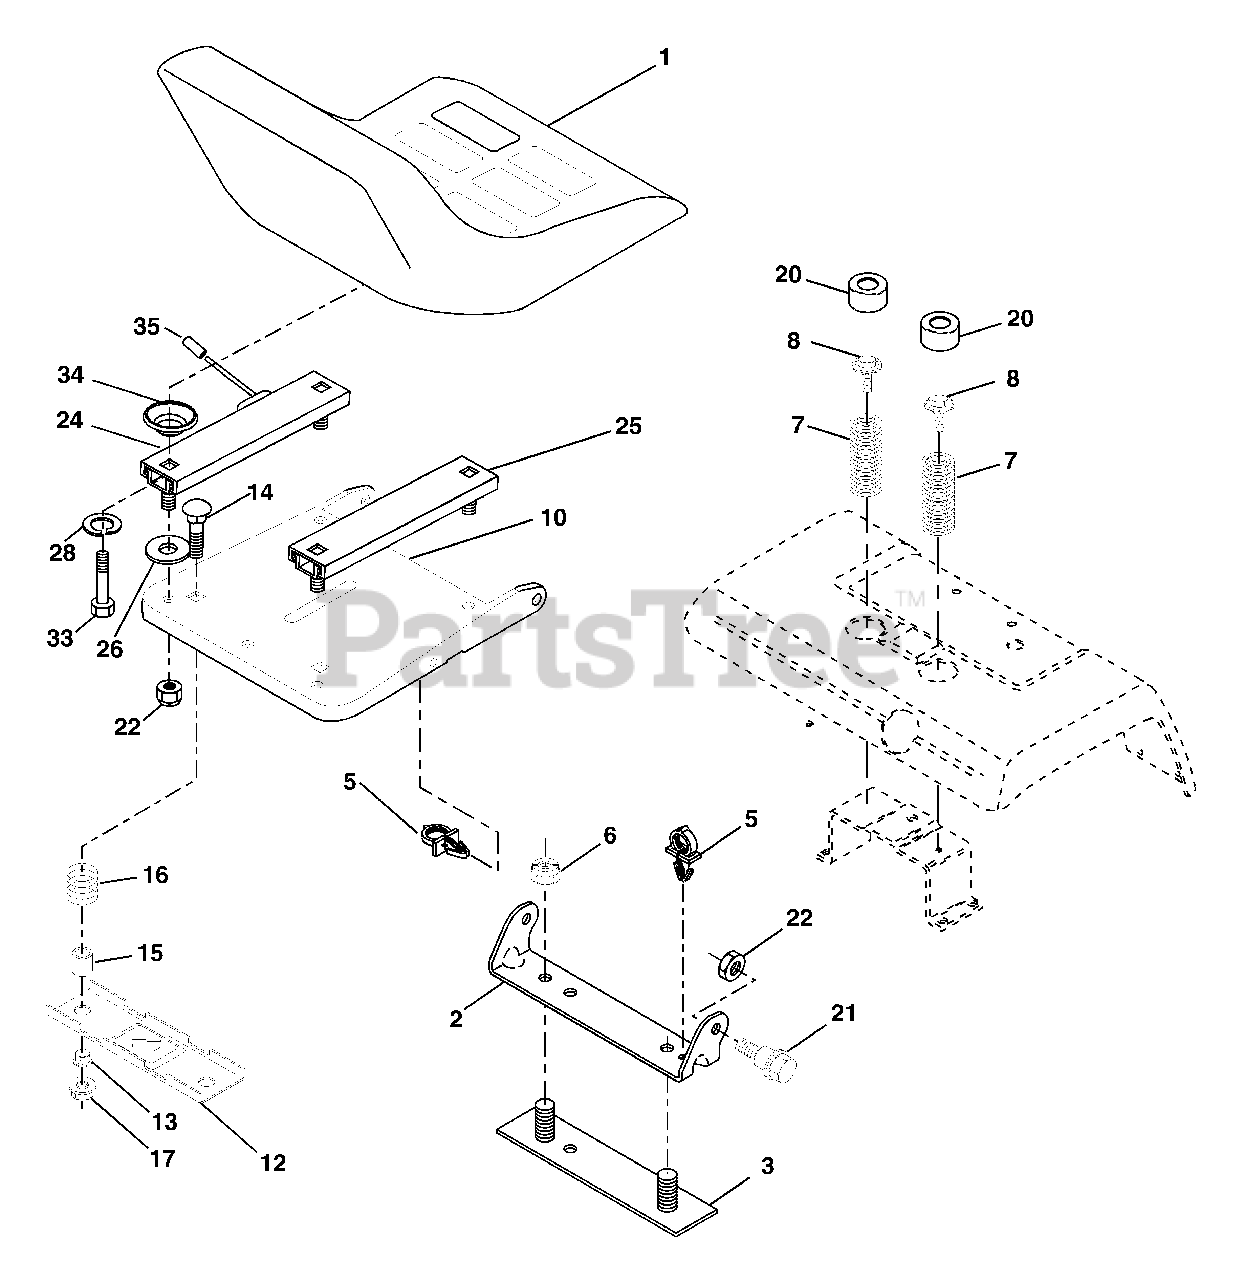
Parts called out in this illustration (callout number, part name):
1	Seat
2	Bracket, Pivot Seat
3	Strap, Fender
5	Clip, Push In Hinged
6	Nut, Crownlock 3/8-16
7	Spring, Seat Cprsn
8	Bolt 5/16-18 UNC X 3/4
10	Pan, Seat
12	Bracket, Mounting Switch
13	Bushing, Snap
14	Bolt, Carriage 1/4-20 X 1-1/2
15	Spacer, Split
16	Spring, Cprsn
17	Nut, Lock 1/4 Lge Flg Gr. 5
20	Cap, Spring Seat
21	Bolt, Shoulder 5/16-18
22	Nut, Crownlock 5/16-18
24	Track Slide Seat LH
25	Track Slide Seat RH
26	Washer 11/32 x 7/8 x 16 Ga.
28	Washer Split
33	Bolt Fin Hex 5/16-18 Unc x 1.00
34	Spacer Seat
35	Cap Vinyl 1 x .34 Red
